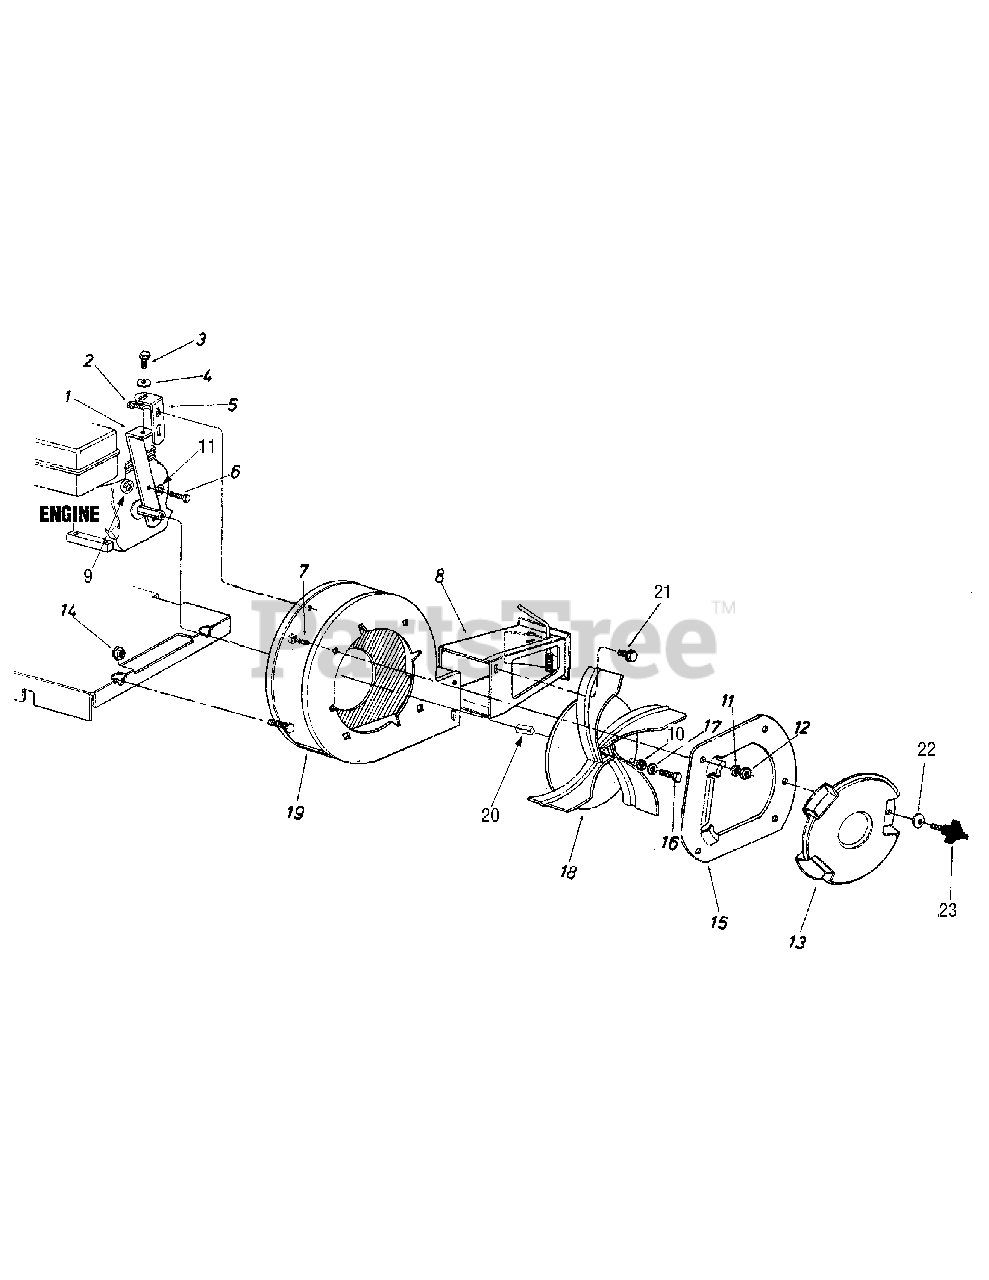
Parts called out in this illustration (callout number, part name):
3	Hex Bolt 5/16-18 x .75
4	Special L-Washer 5/16" x.88 OD
7	Carriage Bolt 5/16-18 x .62
10	Impeller Hub
11	Lock Washer 5/16
12	Hex Nut 5/16-18
13	Blower Guard
14	Hex Shoulder Nut .50"
17	Lock Washer 3/8
21	Hex Sems Bolt 5/16-18 x .62
22	Bell Washer .34 ID x .87 OD
23	Screw 5/16-18 x.75
